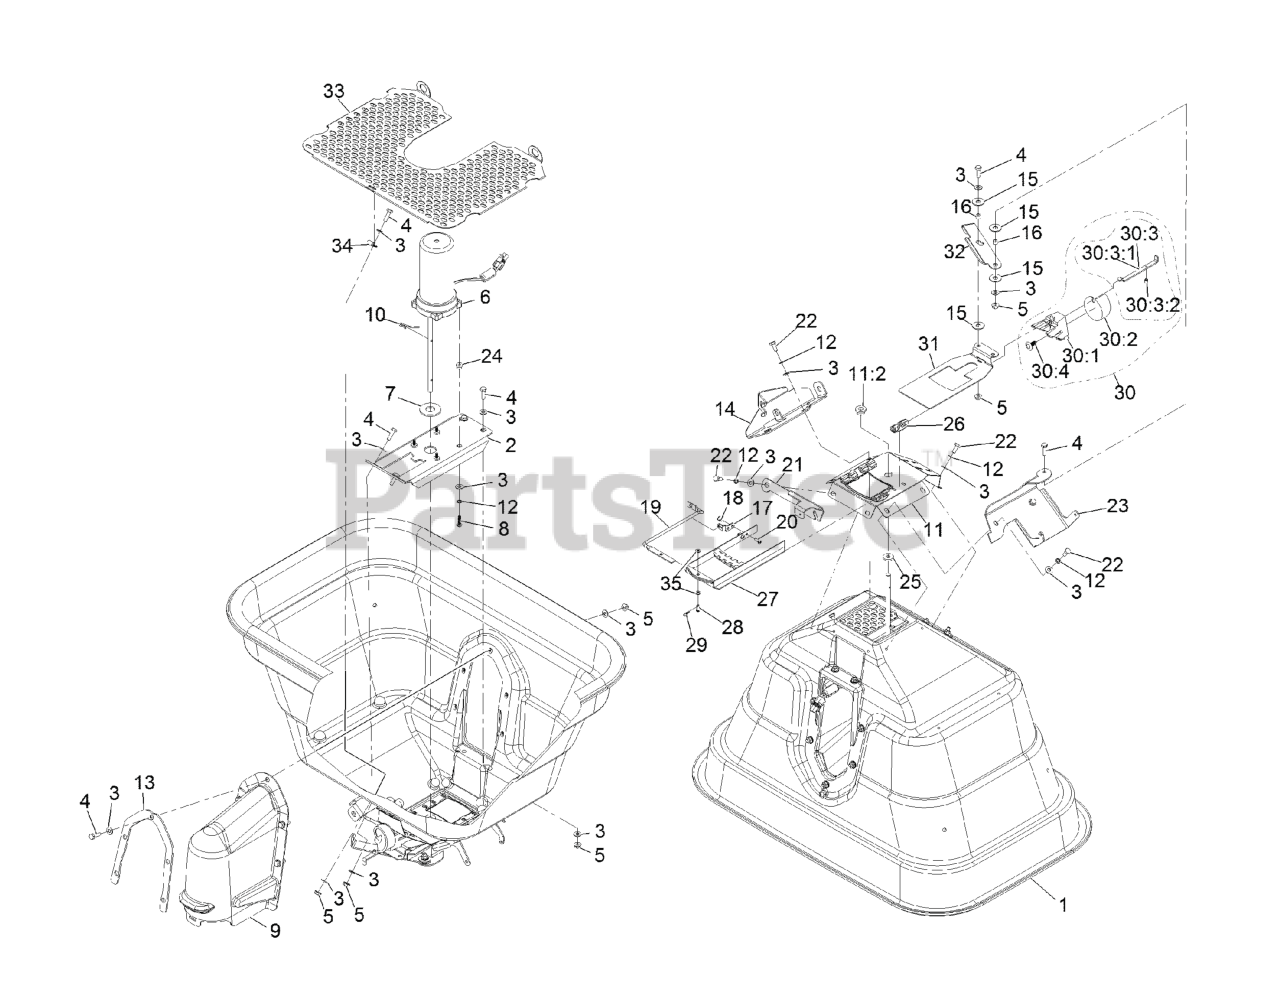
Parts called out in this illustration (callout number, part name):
1	HOPPER-SPREADER, 175 LB (EXMARK)
2	BRACKET-MOUNT, MOTOR
3	WASHER-FLAT
4	SCREW-HH
6	SPREADER MOTOR ASM
8	SCREW-SHWH
9	COVER-MOTOR
10	AGITATOR
11	MULCH PLATE W/ BEARING AS
11:2	BEARING-BOTTOM, HOPPER
12	WASHER-LOCK, INT
13	FLANGE-COVER, MOTOR
14	BRACKET-HOPPER, GATE CONT
17	BRACKET-DIFFUSER
18	NUT-HEX
19	ROD-CONTROL, DIFFUSER
20	SCREW-PPH
21	BRACKET-SPRING, HOPPER DE
22	SCREW-HH
23	BRACKET-LEVER, HOPPER GAT
24	SPACER-FLANGED
25	WASHER-FELT
26	GUIDE-RATE, GATE
27	DIFFUSER
28	PIN-CLEVIS
29	PIN-COTTER, HAIR
30	RATE DIAL ASM
30:1	MOUNT-DIAL
30:2	DIAL
30:3	Rate Gate Link ASM
30:3:1	LINK-GATE, RATE
30:3:2	SCREW-SHOULDER, SLOTTED
30:4	CLIP
31	GATE-RATE
32	LEVER-GATE
33	SCREEN-HOPPER, LARGE HOLE
33	SCREEN-HOPPER, MEDIUM HOL
33	SCREEN-HOPPER, SMALL HOLE
34	CLAMP-LOOP
35	WASHER-FLAT
